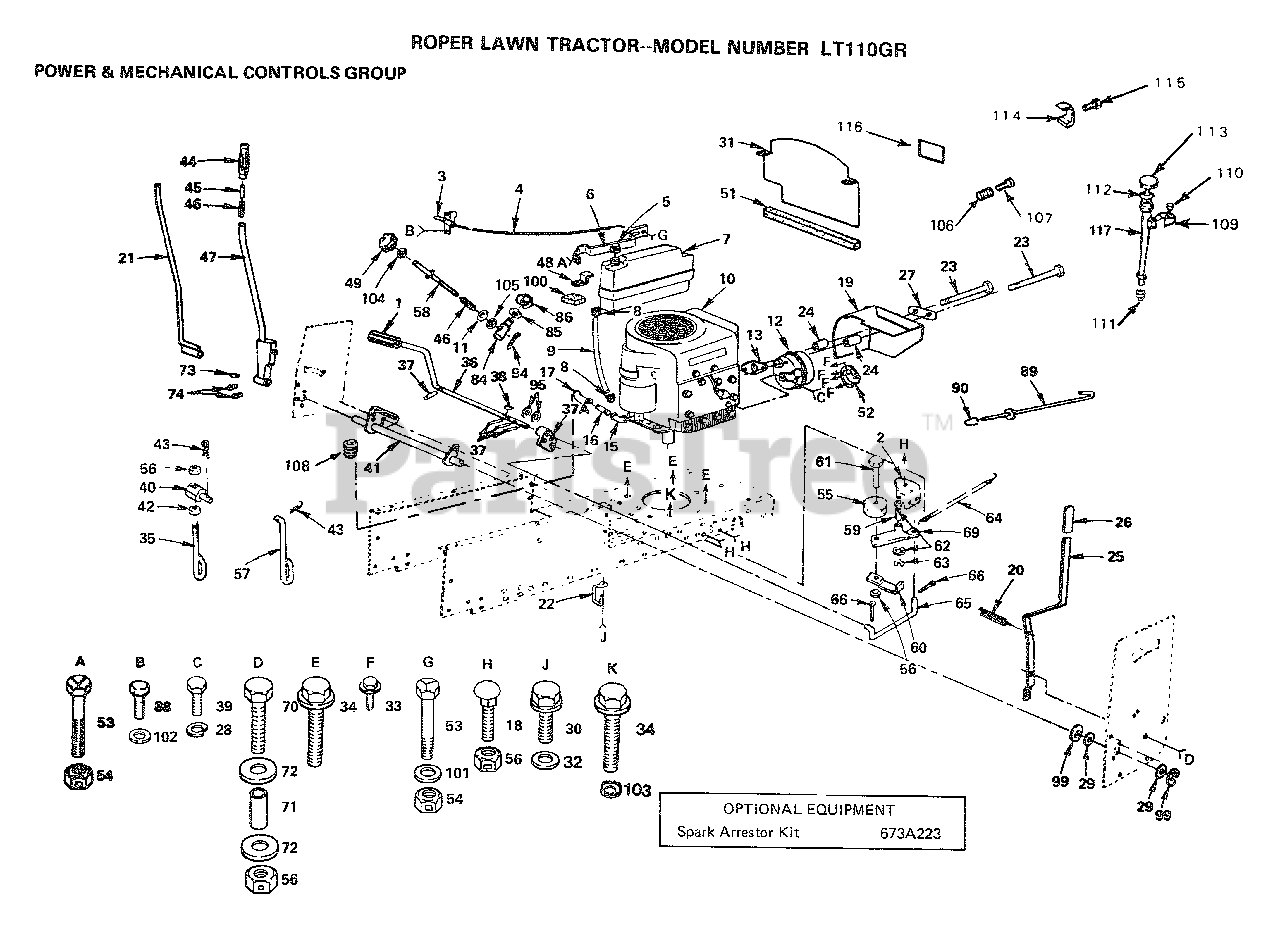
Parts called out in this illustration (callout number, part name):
1	PEDAL COVER T
6	SUPPORT-TANK LT
9	HOSE T
11	WASHER
12	MUFFLER LTV
15	STREET ELBOW LT
16	PIPE NIPPLE
17	ELBOW
18	BOLT
19	BAFFLE ASSY LT
20	"SPRING.EXT.8.5"""
21	ROD ASSY-LEVER LT
23	BOLT YT
24	SPACER LT
27	CLIP-MUFFLER LT
28	LOCKWASHER
29	WASHER
30	SCREW
31	"VERTICAL LT, BAFL"
32	WASHER
33	SCREW LT
34	SCREW
35	LINK LIFT LT
36	FOOT SHAFT PEDAL
37A	ARM BRAKE LT
39	BOLT
42	NUT.HEX.3/8-16UNC
44	GRIP
46	SPRING T
47	LEVER ASSY LT
48	BRACE-TANK LT
52	DEFLECTOR.222573
53	BOLT
57	LIFT LINK LT
58	ROD ADJUST LT
59	"LY, BEARING"
62	WASHER T
63	KLIP RING
64	"SPRING, RETURN LT"
65	"LINK, CLUTCH T"
66	COTTER PIN
85	WASHER
86	KLIP RING
88	SCREW
90	PLUNGER CAP T
99	RING
100	PAD-SPACER T
101	WASHER
103	LOCKWASHER
104	NUT
105	NUT T
106	SPRING, COMPRESSION
108	PLUG T
109	CLAMP, OIL FILL TUBE
